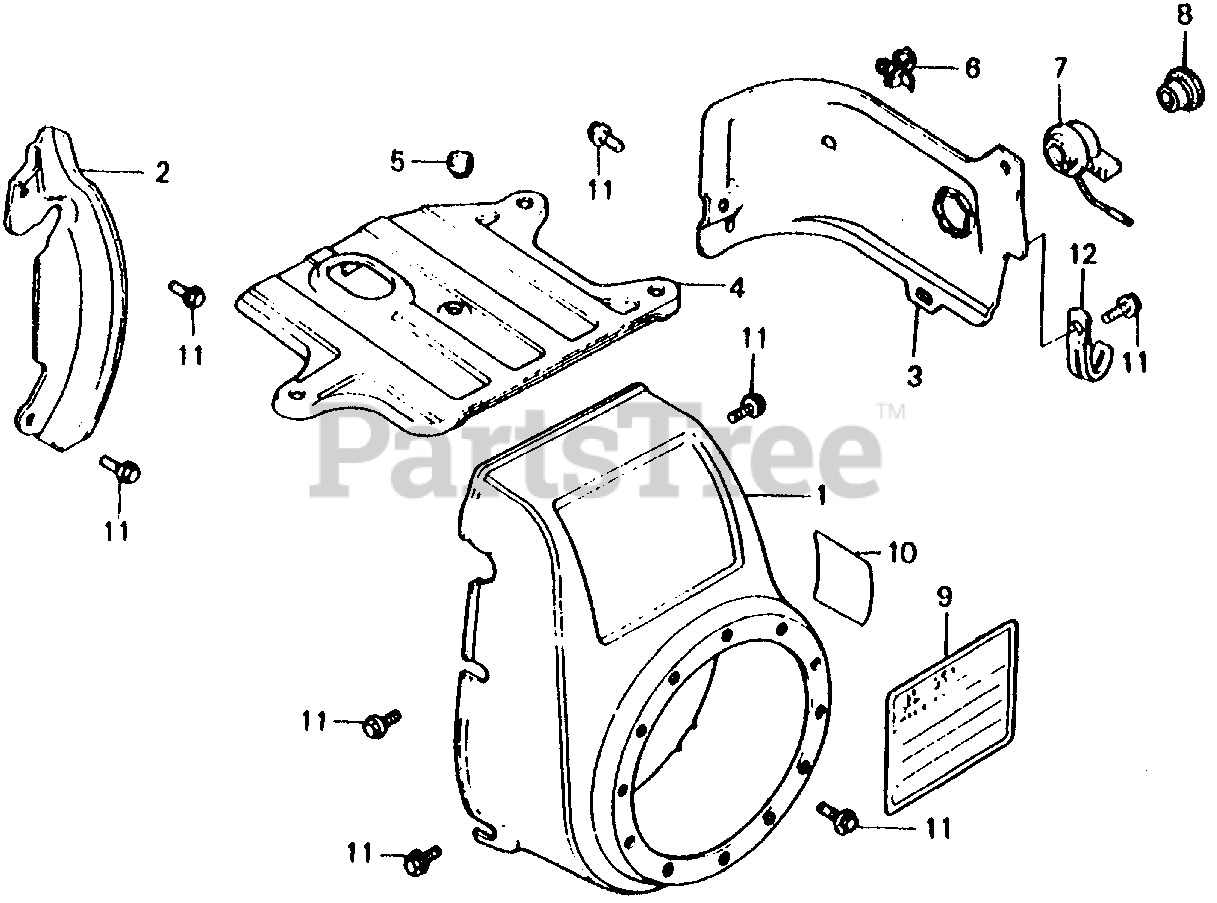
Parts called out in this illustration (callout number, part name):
1	COVER, FAN *R8* (BRIGHT RED)
2	PLATE, SIDE
3	SHROUD
4	COVER, TOP
5	GROMMET, TOP COVER
6	CLIP, IGNITION WIRE (8MM)
7	SWITCH ASSY., ENGINE STOP
8	GROMMET, DRAIN HOLE
9	EMBLEM (ENGLISH/FRENCH)(SPANISH)
10	MARK, OIL CAUTION
11	BOLT, FLANGE (6X12) (CT200)
12	CLIP, CABLE
